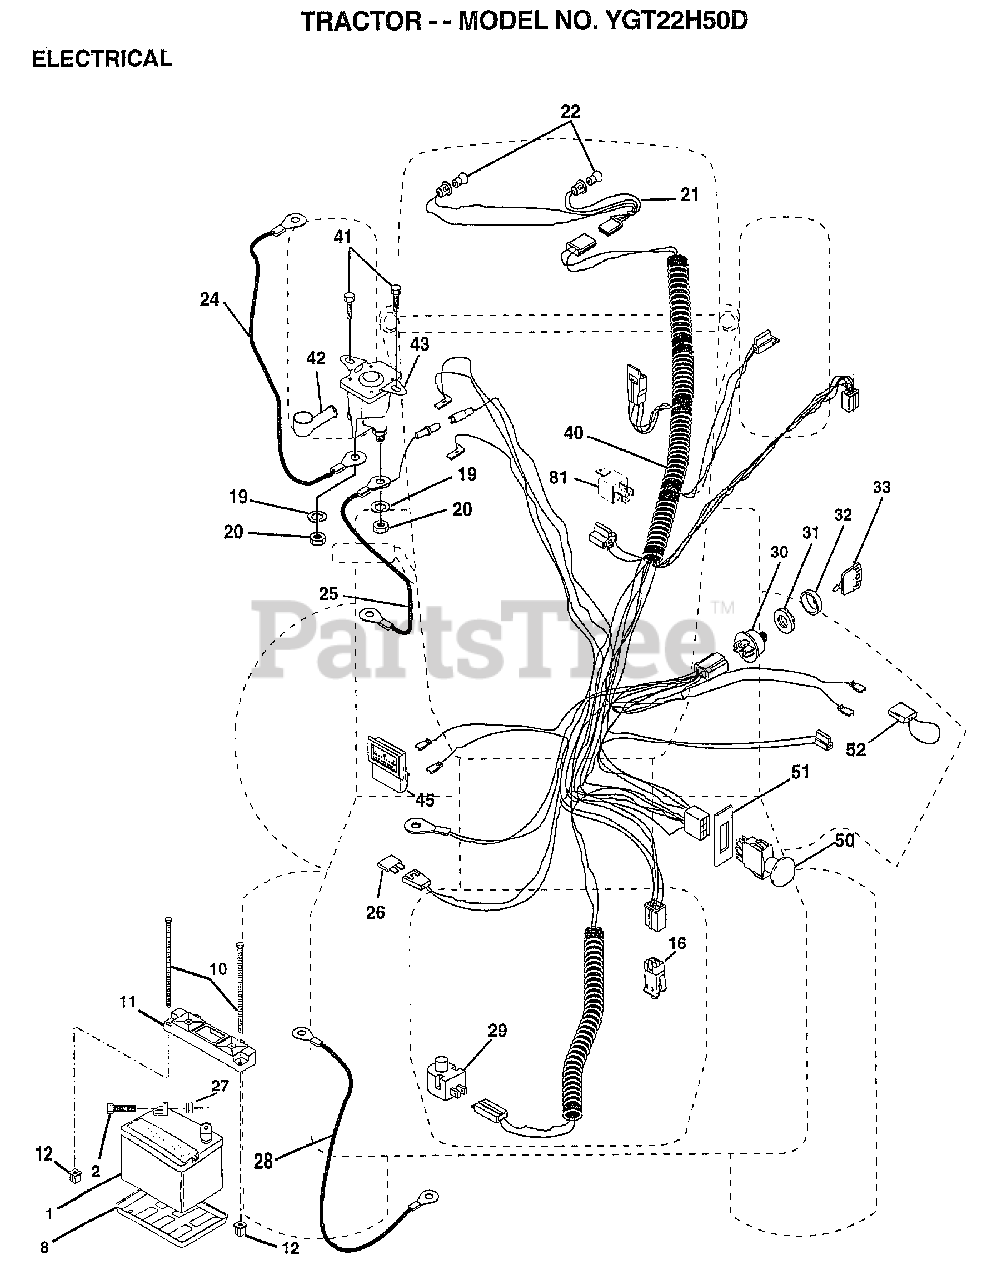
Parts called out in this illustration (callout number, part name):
2	BOLT LT
8	"TRAY T, BATTERY"
11	HOLDDOWN BATTERY
16	SWITCH INTERLOCK
20	NUT
21	HARNESS.ASM.LIGHT W/4152J
22	HEADLAMP BULB
24	CABLE.BATY.22.RED
25	CABLE.BATRY.4GA.
26	FUSE HYT
27	NUT
28	"CABLE BATTERY,GRD"
29	SWITCH.PLUNGER
30	SWITCH.IGN.
31	NUT IGNITION
32	COVER KEY SWITCH
33	KEY MLD GEN DELTA
40	HARNESS.IGN.
41	SCREW
45	AMMETER
50	PTO SWITCH.BLK
51	RING RETAIN PTO
52	PROTECTION LOOP
81	RELAY ASSY T
